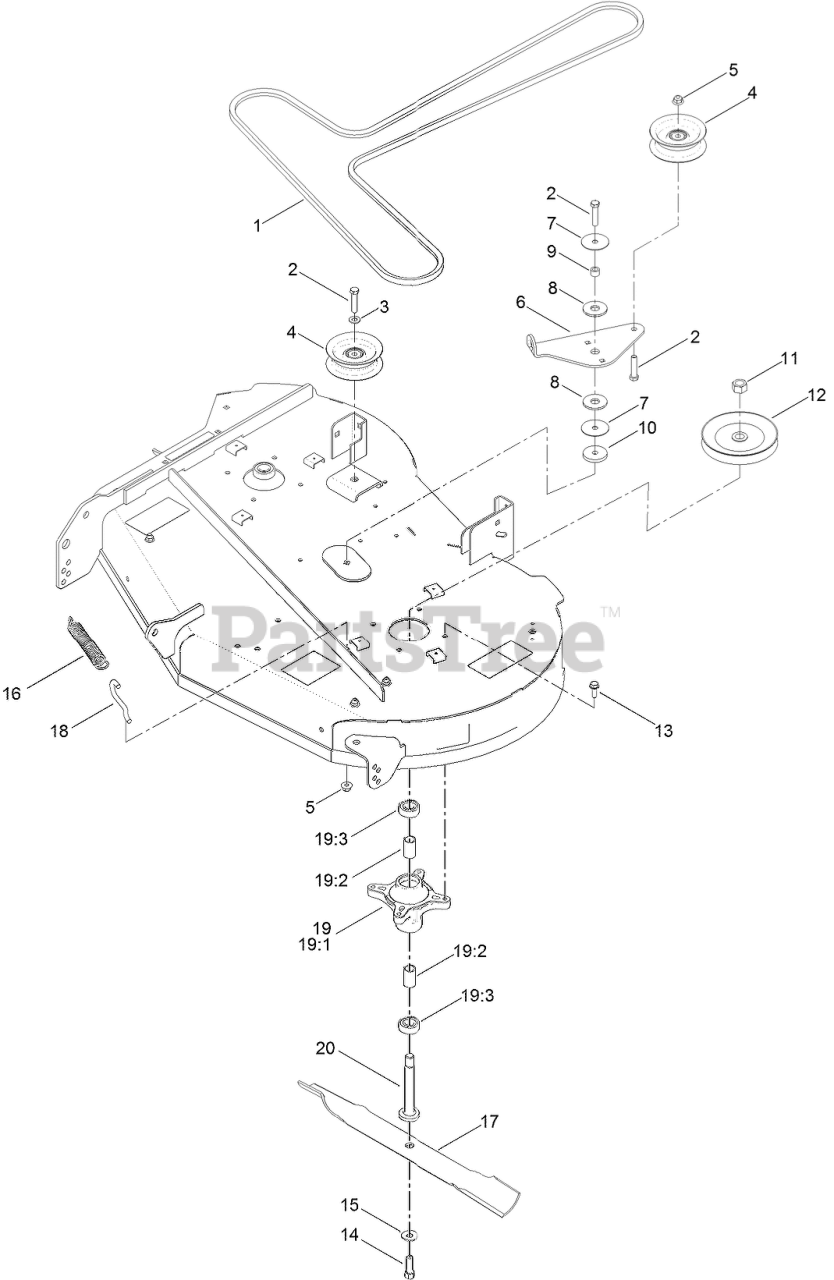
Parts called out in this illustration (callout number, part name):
1	V-BELT
2	SCREW-HH
3	WASHER-FLAT
4	PULLEY-IDLER, FLAT
5	NUT-HF, NI
6	ARM-IDLER
7	WASHER
8	WASHER-FRICTION, COMPOSITE
9	SPACER
10	WASHER-PLAIN
11	NUT-HEX
12	Pulley
13	SCREW-TAPTITE
14	SCREW-HH
15	WASHER-BELLEVILLE
16	SPRING-EXTENSION
17	BLADE-HIGH LIFT
18	HOOK-RETURN, SPRING
19	SPINDLE ASM
19:1	SPINDLE
19:2	SPACER
19:3	BEARING-BALL
20	SHAFT-SPINDLE
